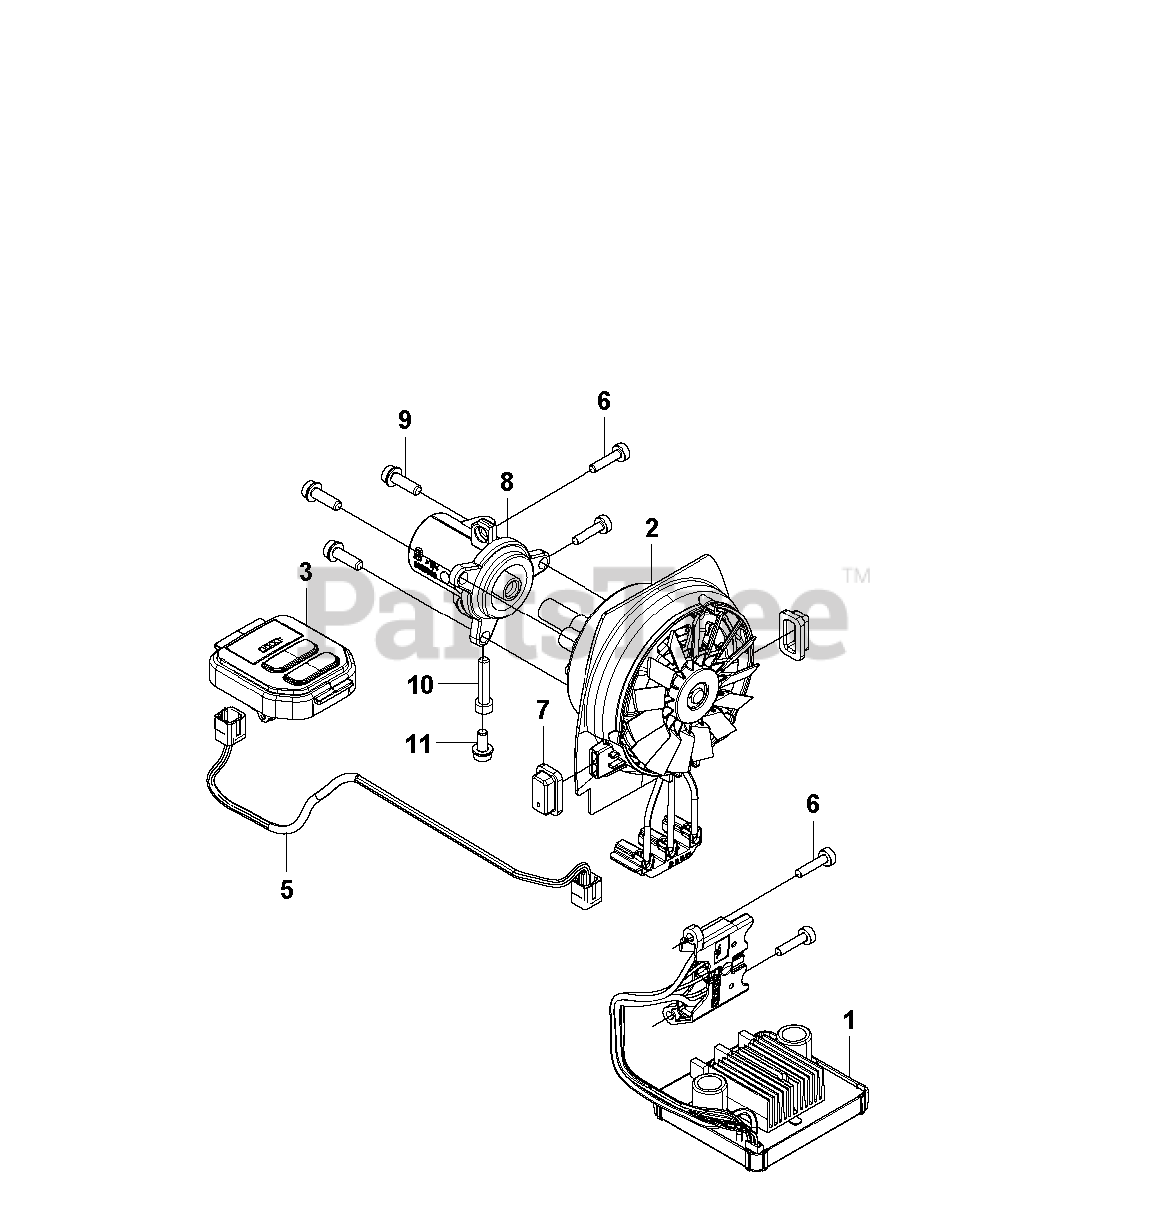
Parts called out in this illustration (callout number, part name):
1	CONTROL PANELS
2	MOTOR ASSY ADAPTER
6	SCREW ITXSCT PW4.2X18 10.9 ZN
10	SCREW ITXSCM M5X25 T27 12.9 T
11	SCREW ITXSCM
